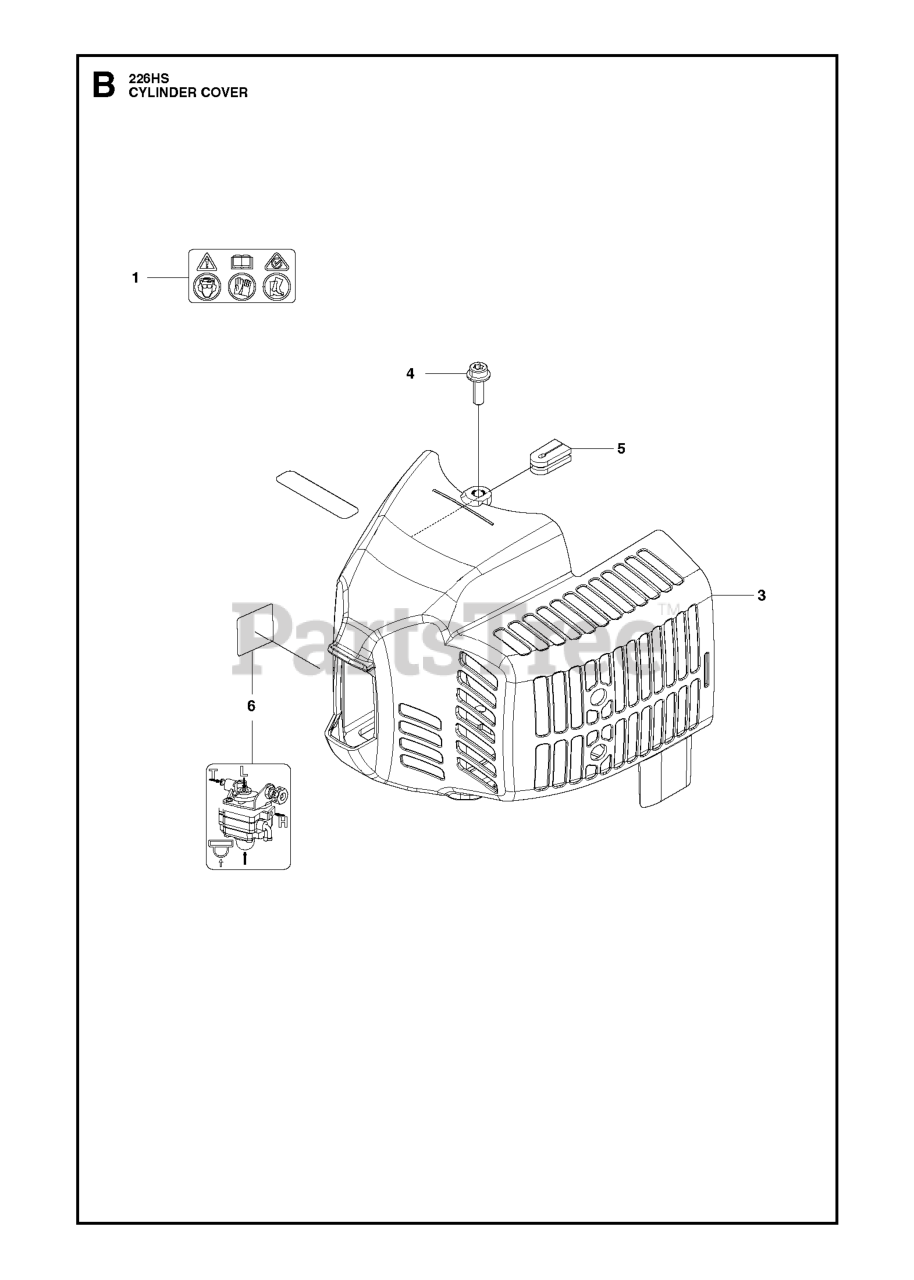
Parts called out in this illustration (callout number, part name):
1	DECAL
3	COVER ENGINE
6	DECAL ADJ LOCATION
